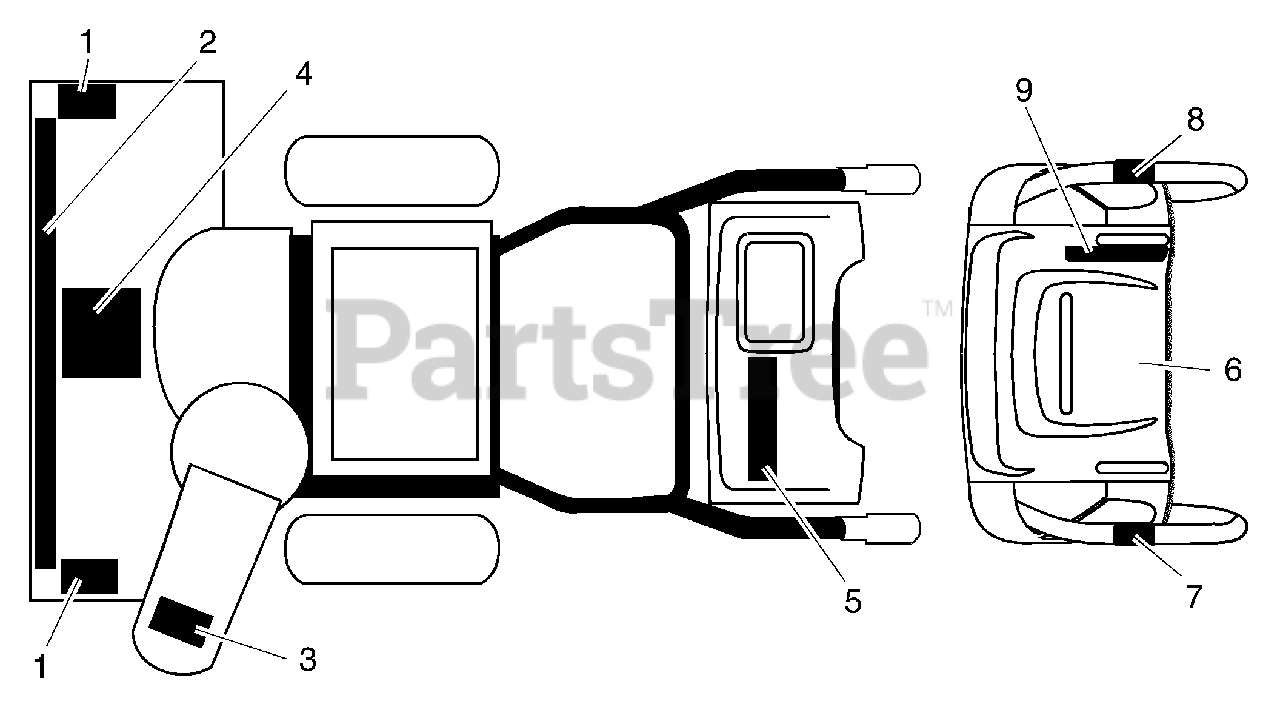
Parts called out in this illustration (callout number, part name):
1	Decal, Danger
2	Decal, Poulan Pro, 5HP/24" (large)
3	Decal, Danger, Deflector
4	Decal, Danger
5	Decal, Poulan Pro, 5HP/24" (small)
6	Decal, Instruction
7	Decal, Traction Lever
8	Decal, Auger Lever
9	Decal, Speed Control
